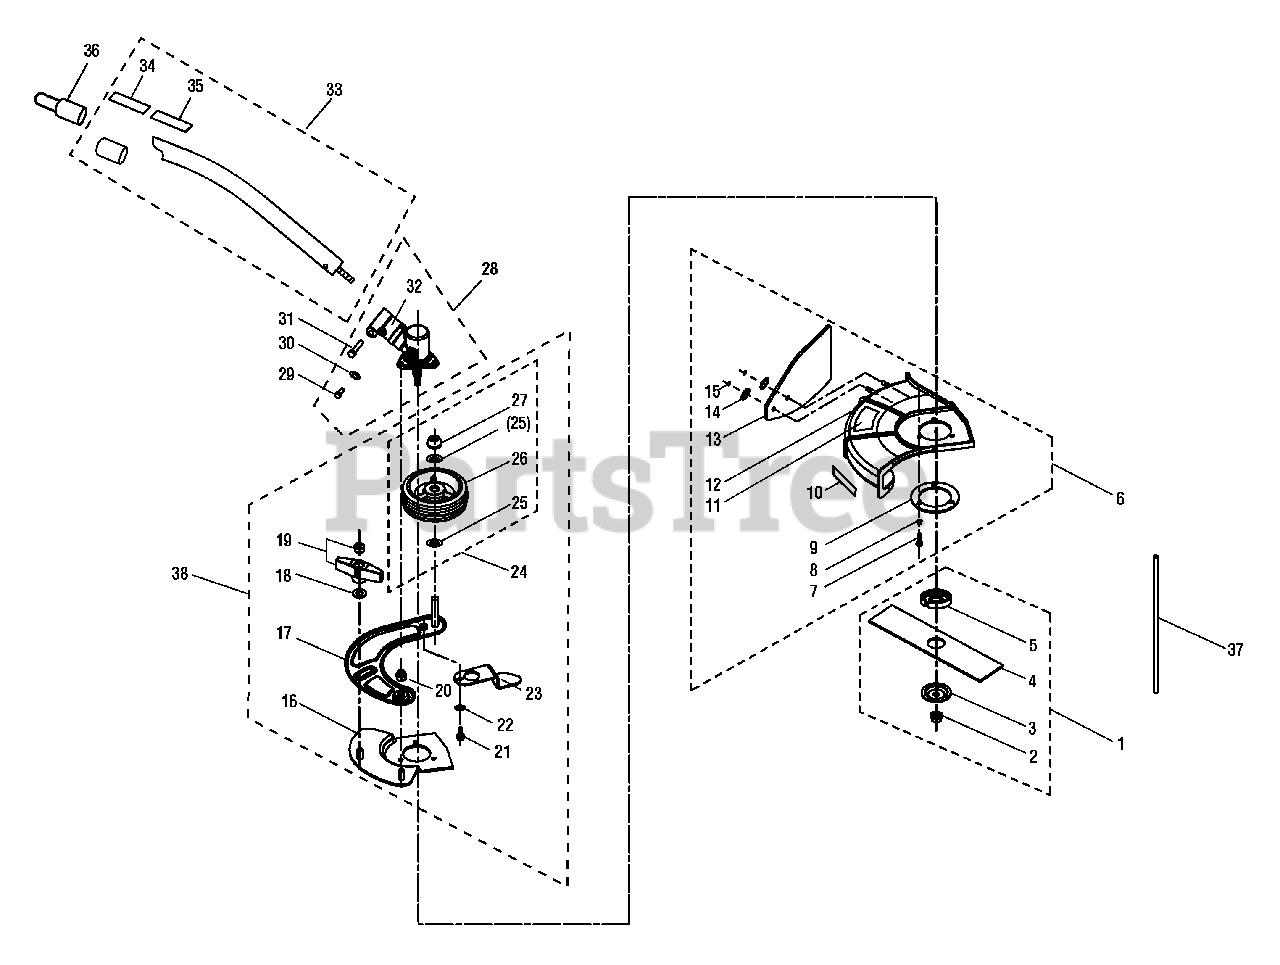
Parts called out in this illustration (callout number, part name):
1	Blade Assembly
2	Lock Nut (M8)
3	Cupped Washer
4	Blade
5	Flanged Washer
6	Blade Guard Assembly
7	Screw (10-24 X 5/8 in. Hex Hd.)
8	Lock Washer (5 mm)
10	Warning Decal
11	Expand-it Logo Label
12	Blade Guard
14	Washer (6 mm)
15	Hex Nut (M6)
16	Support Plate
17	Wheel Mounting Plate
18	Washer (10 mm)
19	Adjusting Knob With Hex Nut
20	Hex Lock Nut (M8)
21	Screw (M5 X 16 mm Hex Hd.)
22	Washer (5 mm)
24	Wheel Assembly
25	Washer (10 mm)
27	Push Nut (10 mm)
28	Gear Head & Screw Assembly
29	Screw (M5 X 12 mm Hex Hd.)
30	Lock Washer (5 mm)
31	Cap Screw (M6 X 30 mm)
32	Gear Head Assembly
33	Boom Assembly
34	Warning Decal
35	Warning Label (UL)
36	Hanger Cap
37	Holding Pin
38	Support Arm Assembly
